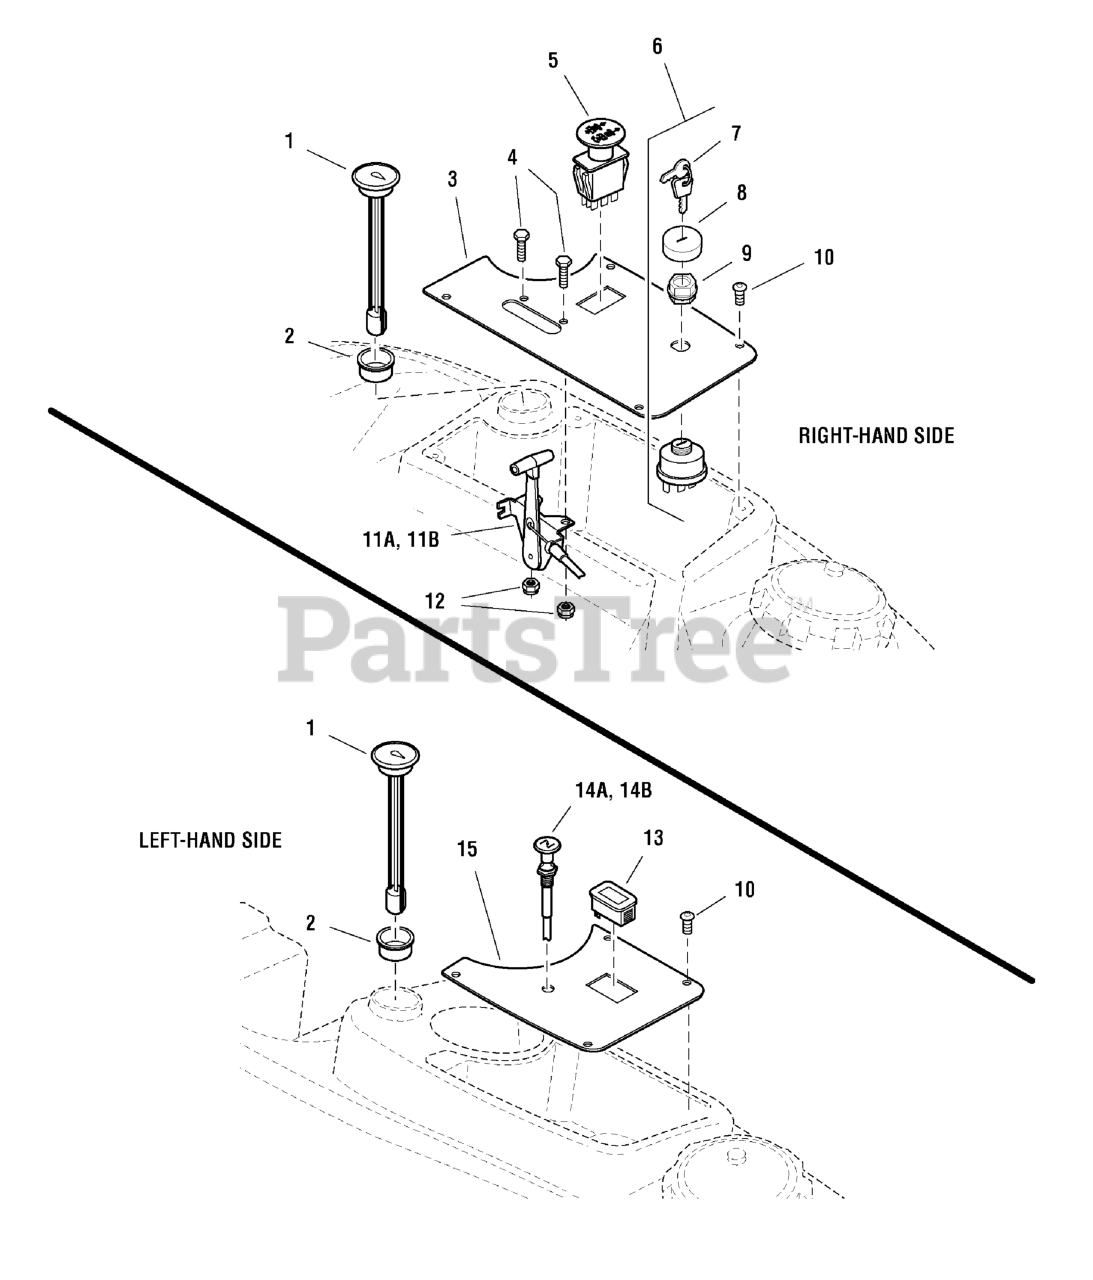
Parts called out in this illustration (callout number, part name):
1	GAUGE, FUEL, 12
2	GROMMET
3	CONTROL PANEL-RH
4	BOLT, 1/4-20 x 3/4
5	SWITCH, BLADE ENGAGEMENT
6	SWITCH, IGNITION, 6 POST
7	KEY, IGNITION MOLDED SET
8	COVER, PLASTIC, SNAP ON
9	PLASTIC NUT
10	SCREW, Allen Head, 1/4-20 x 1/2
11A	CABLE, Throttle, 38"
11B	CABLE, Throttle, 45"
12	NUT, 1/4-20 HEX SERR. FLANGE
13	HOUR METER
14A	CABLE, Choke Control, 39-1/2"
14B	CABLE, CHOKE CONTROL, 56
15	CONTROL PANEL-LH
